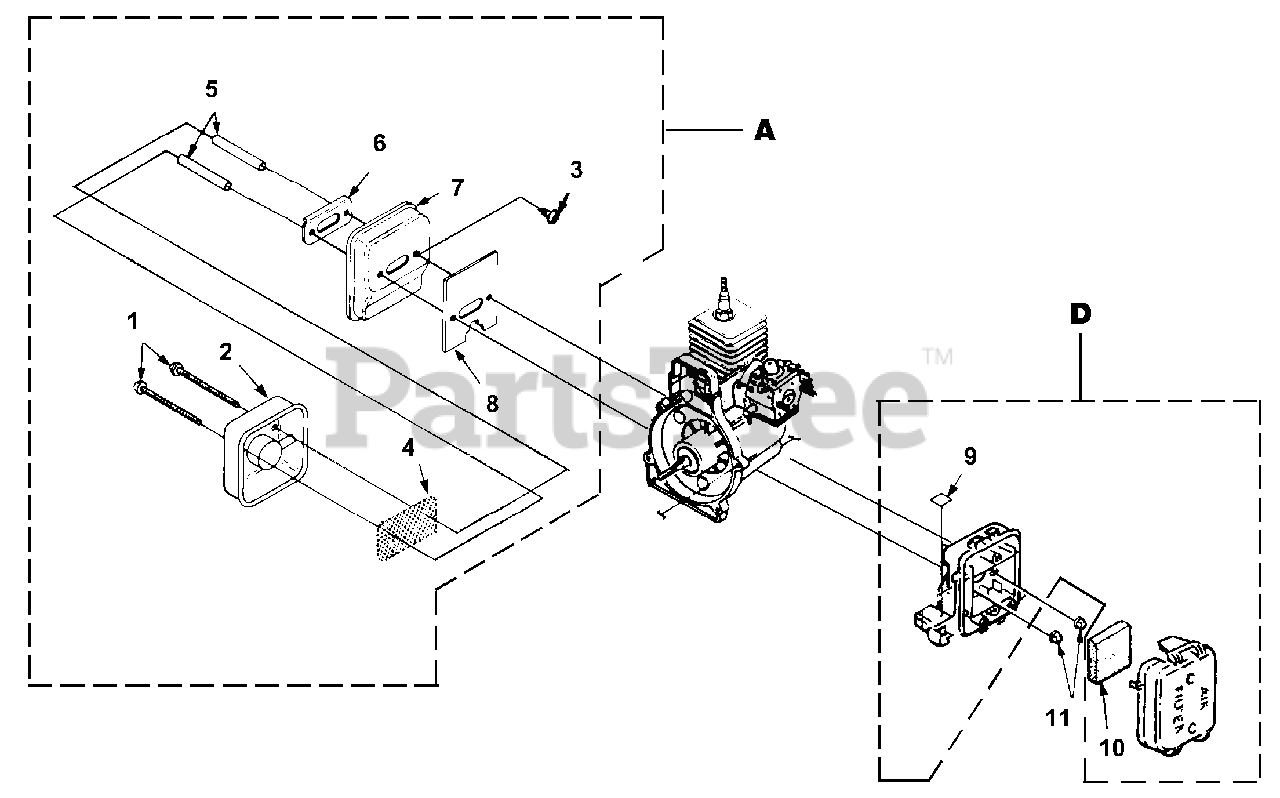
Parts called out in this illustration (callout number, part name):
1	SCREW-Sems Hex Hd. (10-24 X 2 1/2")
2	MUFFLER-Cover
4	SCREEN-Spark
5	SPACER-Muffler
6	PLATE-Reinforcing
7	MUFFLER BODY
8	GASKET-Muffler
9	DECAL-Choke
10	FILTER-Air
11	NUT-Locking Hex (10-24)
A	MUFFLER-Complete
D	AIR FILTER BOX
